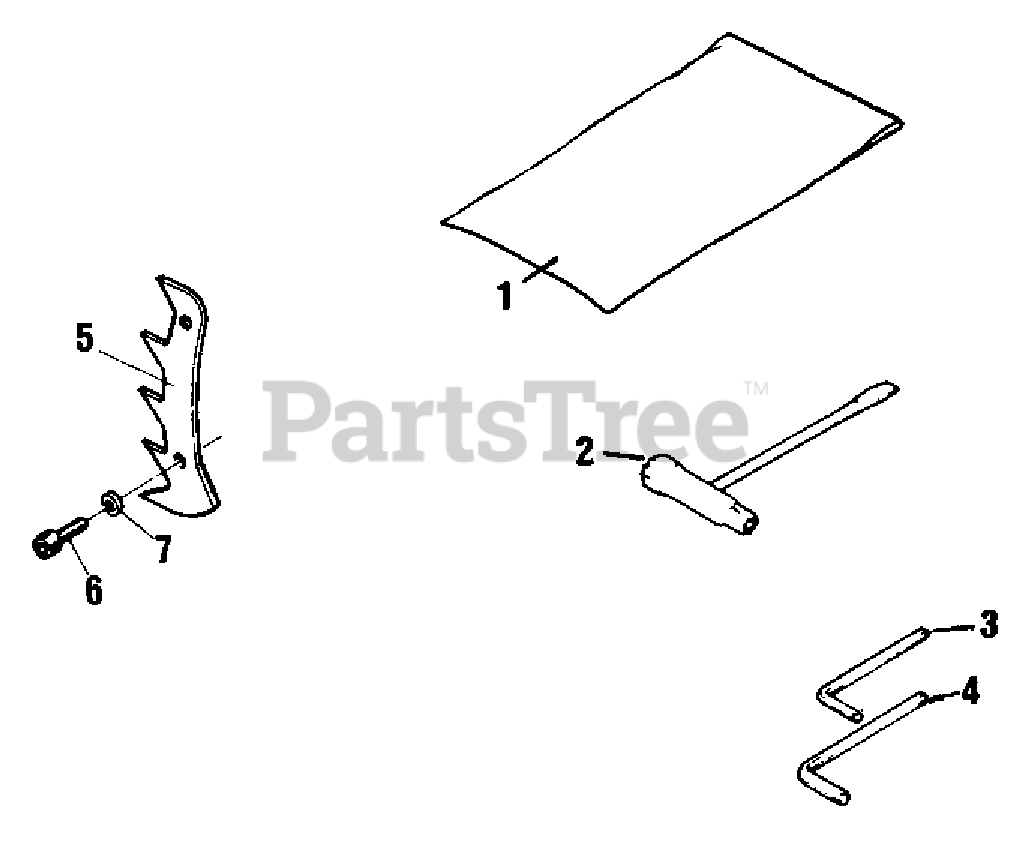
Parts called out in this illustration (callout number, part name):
1	BAG, TOOL
2	T-WRENCH
3	WRENCH - 3
4	WRENCH - 4
6	BOLT 5×12
7	WASHER, SPRING 5
